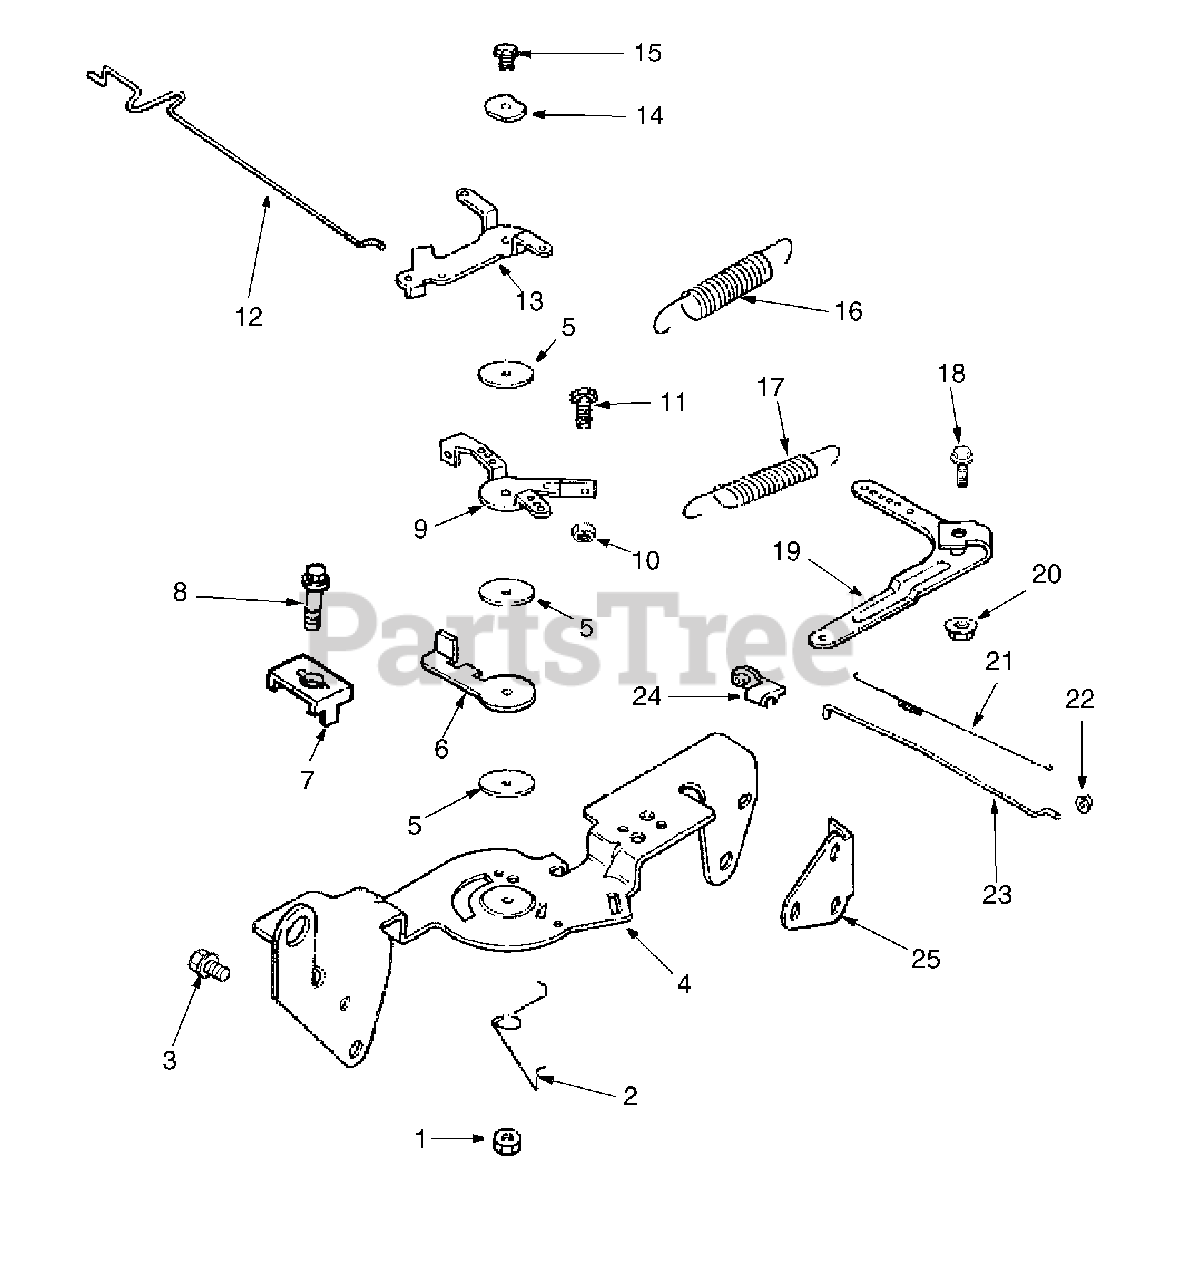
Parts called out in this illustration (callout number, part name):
1	Nut, Hex Lock M5 x 0.8
2	Spring, Choke Return
3	Screw, Hex Flange M6 x 1.0 x 16
4	Bracket, Control
5	Washer, Plain 5.5 mm
6	Lever, Throttle Actuator
7	Clamp,Cable,
8	Screw, Hex Flange M5 x 0.8 x 16
9	Lever, Throttle Control
10	Nut, Hex M4 x 0.7
11	Screw, Hex Cap M4 x 0.7 x 30
12	Linkage, Choke
13	Lever, Choke
14	Washer, Spring 1/4"
15	Screw, Hex Flange M5 x 0.8 x 20
16	Spring, Throttle Limiter
17	Spring, Governor
18	Screw, Hex Flange M6 x1.0 x 25
19	Lever, Governor
20	Nut, Hex Flange M6 x 1.0"
21	Spring, Linkage
22	Bushing, Linkage Retaining
23	Linkage, Throttle
24	Bushing, Linkage Retaining
25	Bracket Support
